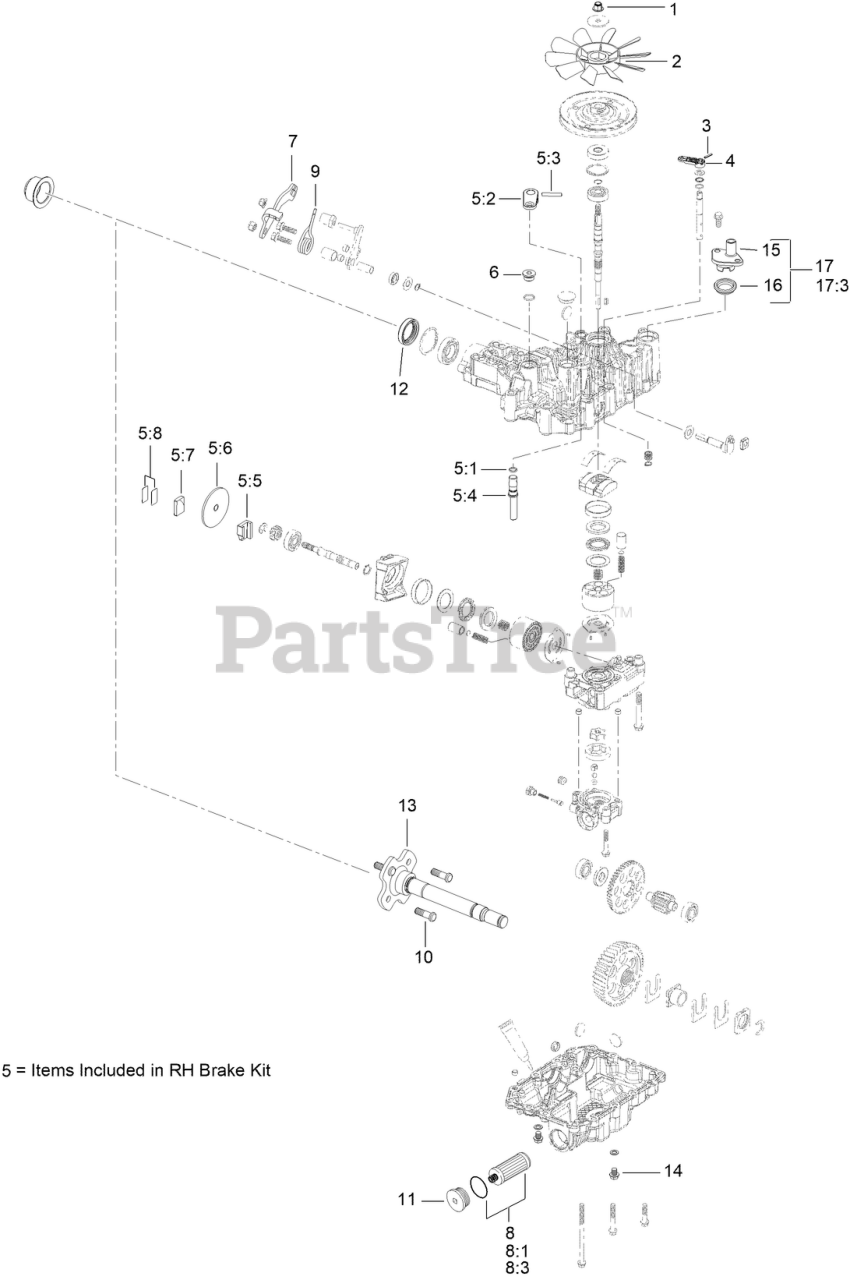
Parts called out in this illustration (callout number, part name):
1	NUT-LOCK
4	LEVER-BYPASS
5	RH BRAKE KIT
5:1	O-RING
5:2	ARM-BRAKE
5:3	Pin-Roll
5:4	SHAFT-BRAKE
5:5	ACTUATOR-BRAKE
5:6	DISC-BRAKE
5:7	SHOE-BRAKE
5:8	SHIM KIT
6	CAP-OIL
7	LEVER-CONTROL, RH
8	2 TRANSMISSION FILTER KIT
8:3	SEALING WASHER
9	SPRING-TORSION
10	STUD-WHEEL
11	CAP-OIL FILTER
12	SEAL-AXLE, UA
14	DRAIN BOLT
15	EXPANSION FITTING
16	GROMMET SEAL, EXPANSION FITTING
17	EXPANSION FITTING - W/ SEAL
17:3	M8*20 FLANGE BOLT
